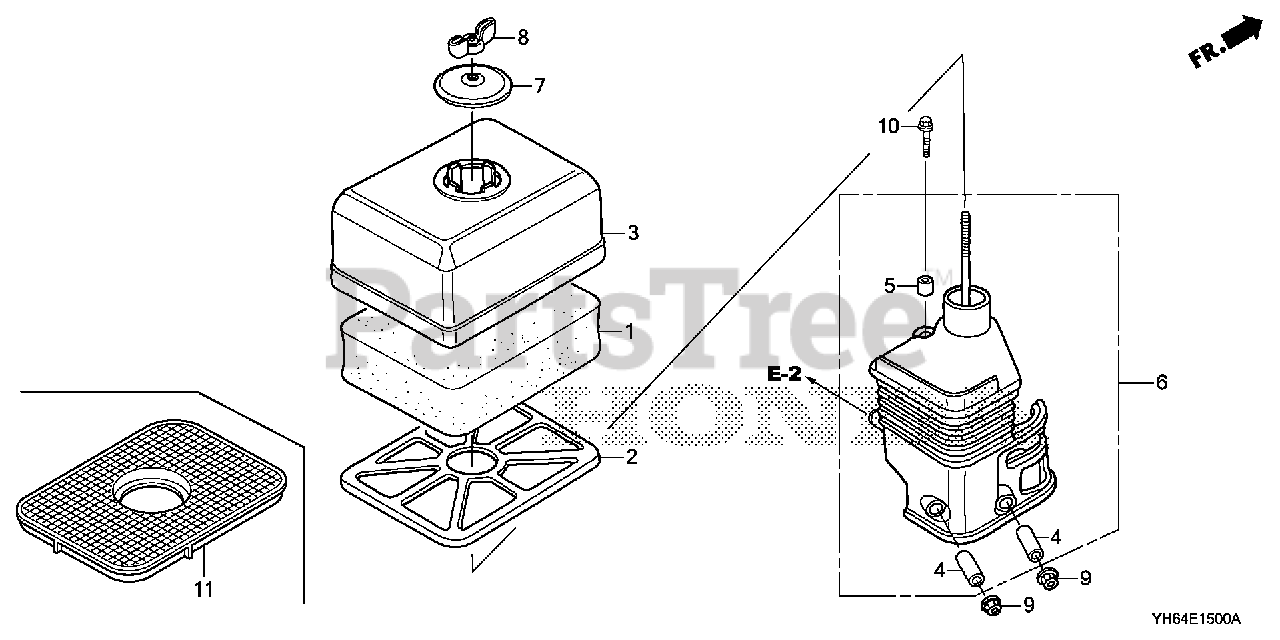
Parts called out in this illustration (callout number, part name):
1	ELEMENT, AIR CLEANER (SEMI-DRY)
3	COVER, AIR CLEANER (SEMI-DRY)
4	COLLAR, AIR CLEANER Use from Engine SN 1786085.
5	COLLAR B, AIR CLEANER
6	ELBOW, AIR CLEANER
7	CAP, CLEANER
8	WINGNUT, TOOL BOX SETTING
9	NUT, FLANGE (6MM)
10	BOLT, FLANGE (6X20)
11	GRID, AIR CLEANER
